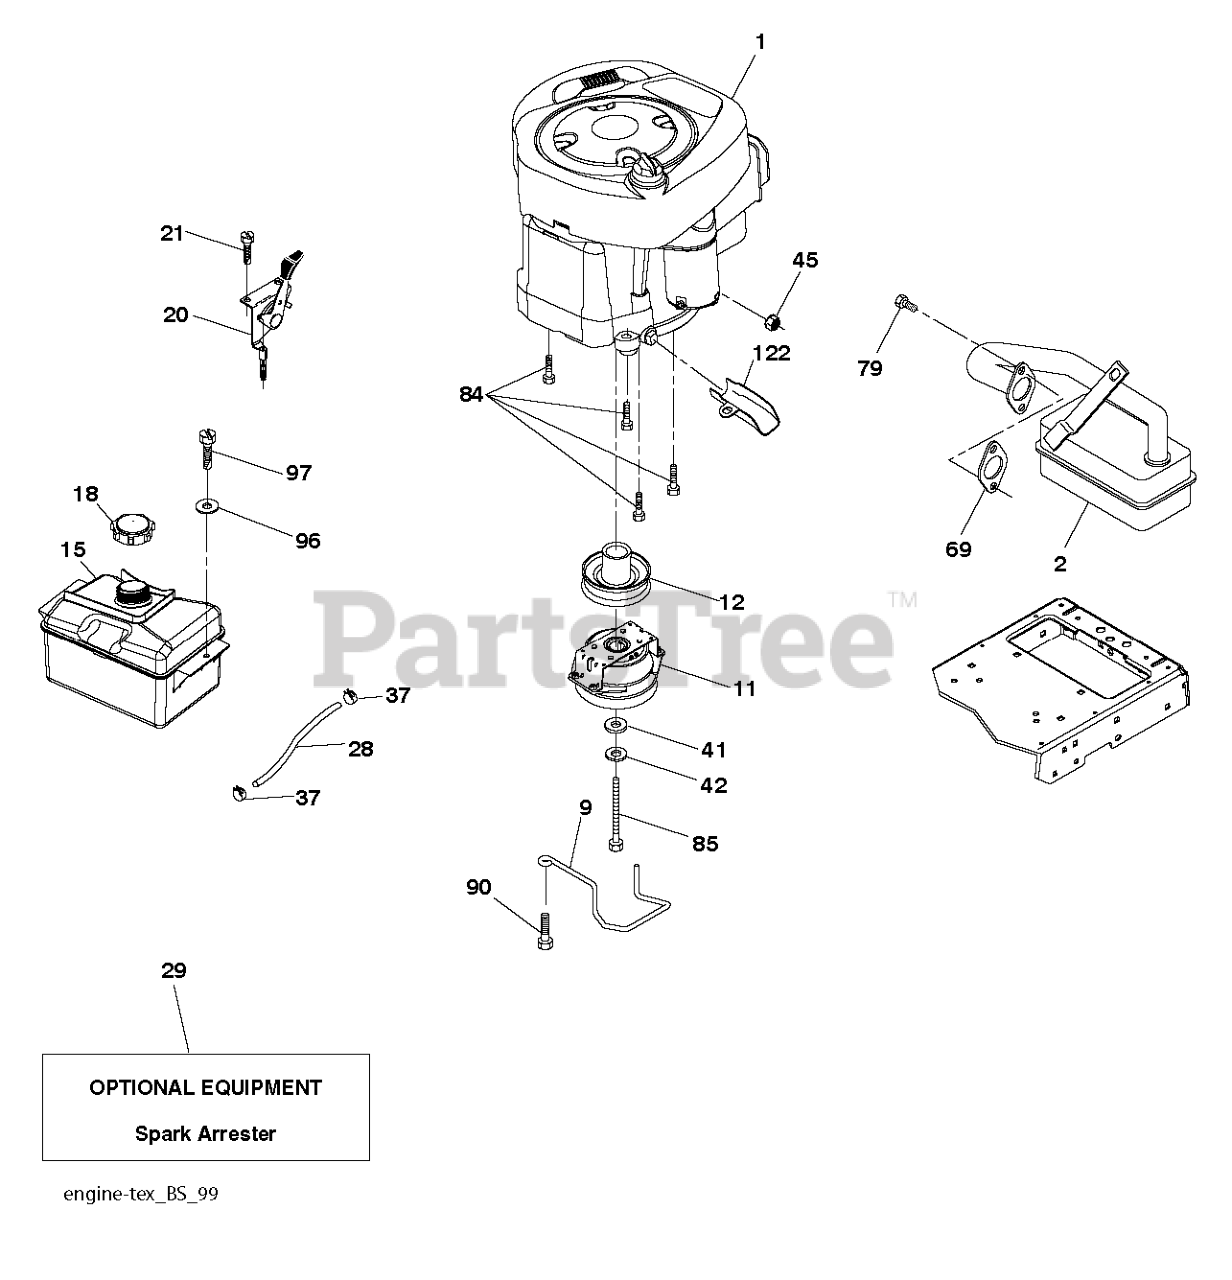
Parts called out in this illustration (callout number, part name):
2	MUFFLER.B&S.MODEL.21.11HP.OHV
9	KEEPER.BELT.ENGINE.3.25 (3 2)
11	RB.CLUTCH.OGURA.4.4.PD
12	PULLEY.ASM.ENG.OGURA.3
15	FUEL.TANK.ASM.NON-EPA
18	CAP ASM.FUEL.2.25"FR.
20	CONTROL.TH/CK.C.
21	SCREW.#10 X 0.750.BOS
28	LINE.FUEL.20
29	KIT.SPARK ARRESTOR 794945 B&S
37	HOSE CLAMP
42	LOCKWASHER
45	NUT
69	REPL BY 532 27 22-93
79	SCREW.SOCKET HD.5/16-1
84	SCREW.3/8-16
85	BOLT HEX 7/16-20X4-1/4"
90	SCREW 3/8-16X1
96	WASHER
97	SCREW HEXWSHR 1/4-20X3/4
122	EXTENSION DRAIN OIL
